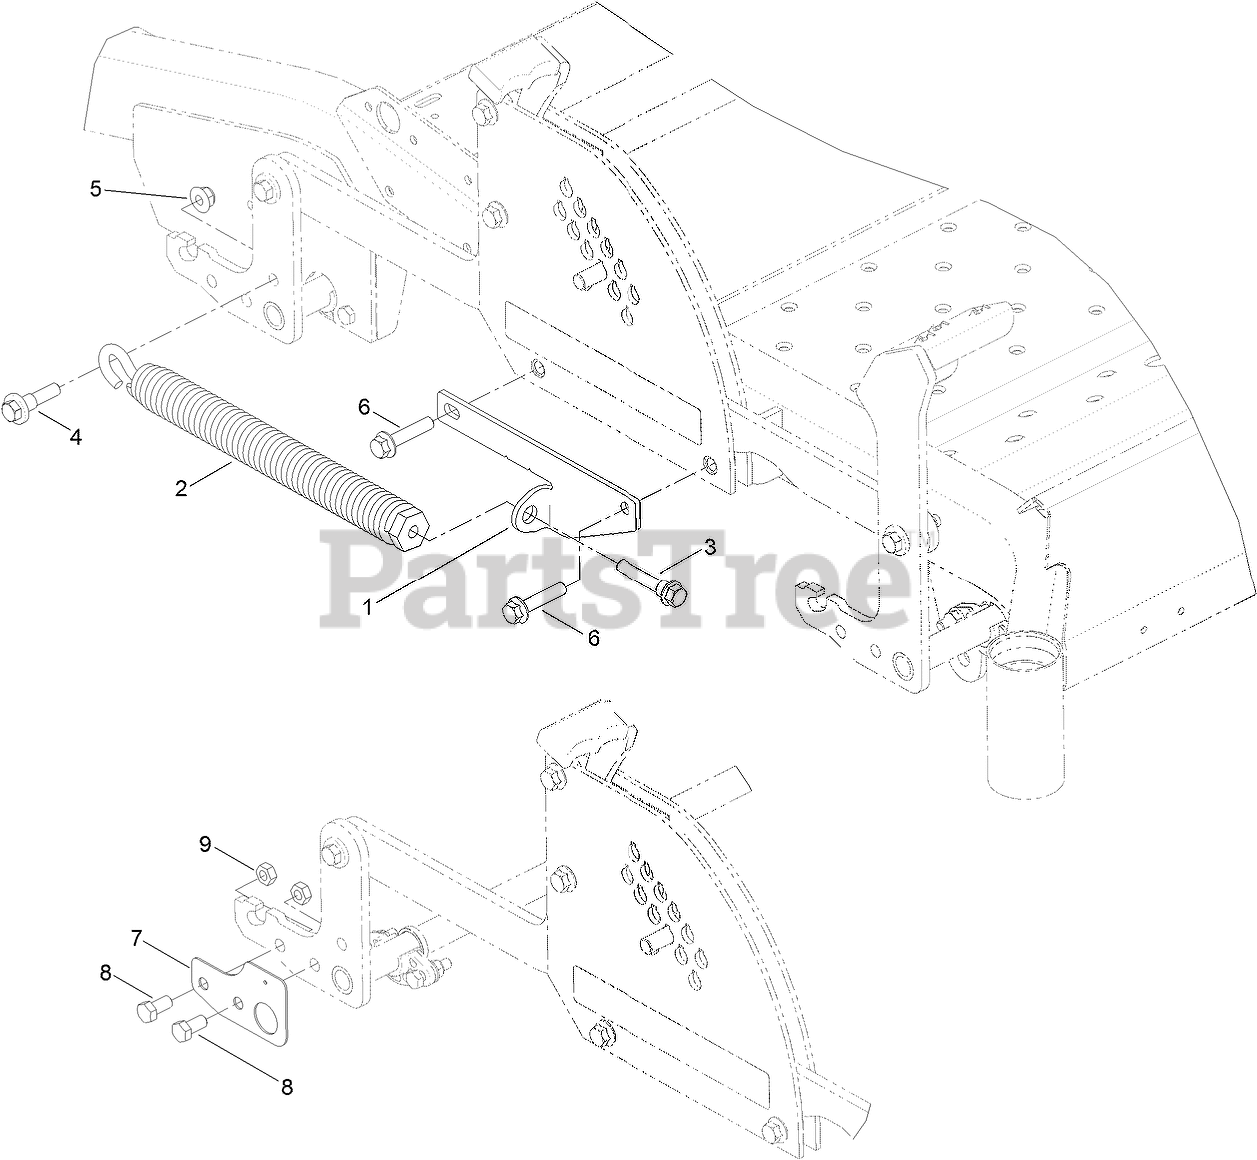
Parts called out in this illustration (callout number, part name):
1	SUPPORT-SPRING
2	SPRING-EXTENSION
3	BOLT-SHOULDER
4	BOLT-SHOULDER
5	NUT-HF, NI
6	SCREW-HHF
7	TEMPLATE
8	SCREW-HH
9	NUT-HEX
